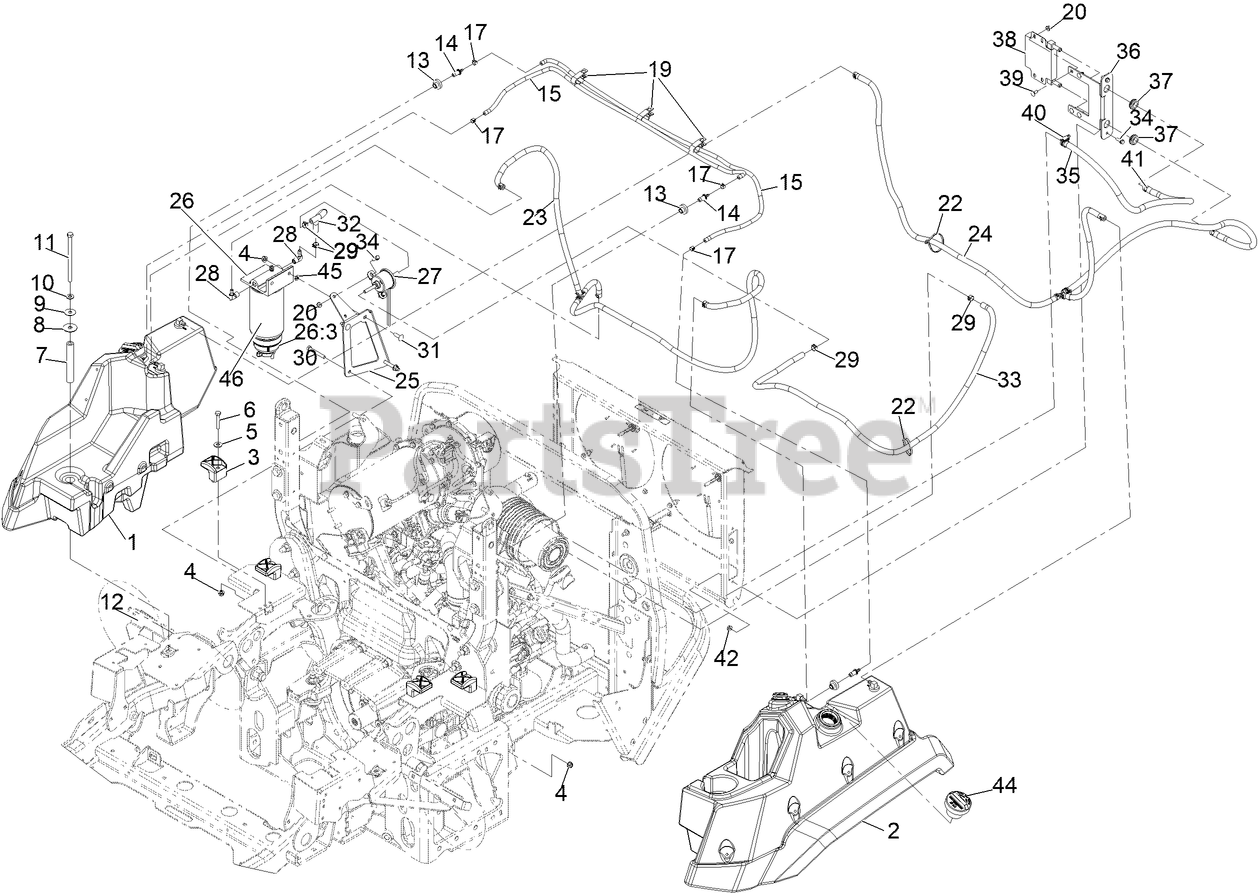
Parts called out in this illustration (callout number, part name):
1	RH FUEL TANK ASM
2	ASM-FUEL TANK, LH
4	NUT-HF, NI
5	WASHER-FLAT
6	SCREW-HH
7	TUBE-SPACER
8	WASHER-RUBBER
9	WASHER-PLAIN
10	WASHER-FLAT
11	SCREW-HH
12	NUT-HF, NI
13	BUSHING
14	FITTING-ORIFICE, STRAIGHT
15	HOSE-VENT, TANK
17	CLAMP-HOSE
19	CLAMP-HOSE
22	TIE-CABLE
23	FUEL SUCTION LINE ASM
24	HOSE ASM-FUEL, TEE
25	BRKT-FUEL FILTER
26	FILTER-FUEL/WATER SEPARATOR
26:3	FILTER-BOWL, WATER SEPARATOR
27	PUMP-FUEL, ELECTRIC
28	FITTING-HYD, 90
29	CLAMP-HOSE
30	SCREW-HH
31	SCREW-CARR
32	HOSE-FUEL
33	HOSE-FUEL
34	SCREW-HWH
35	HOSE-FUEL
36	MOUNT-COOLER, FUEL
37	GROMMET
38	COOLER-OIL
39	SCREW-CARR
40	Clamp-Hose
41	CLAMP-HOSE
44	CAP-FUEL, DIESEL ULTRA LOW SULFUR
45	RING-RETAINING, BOLT
46	FILTER-FUEL/WATER SEP.
